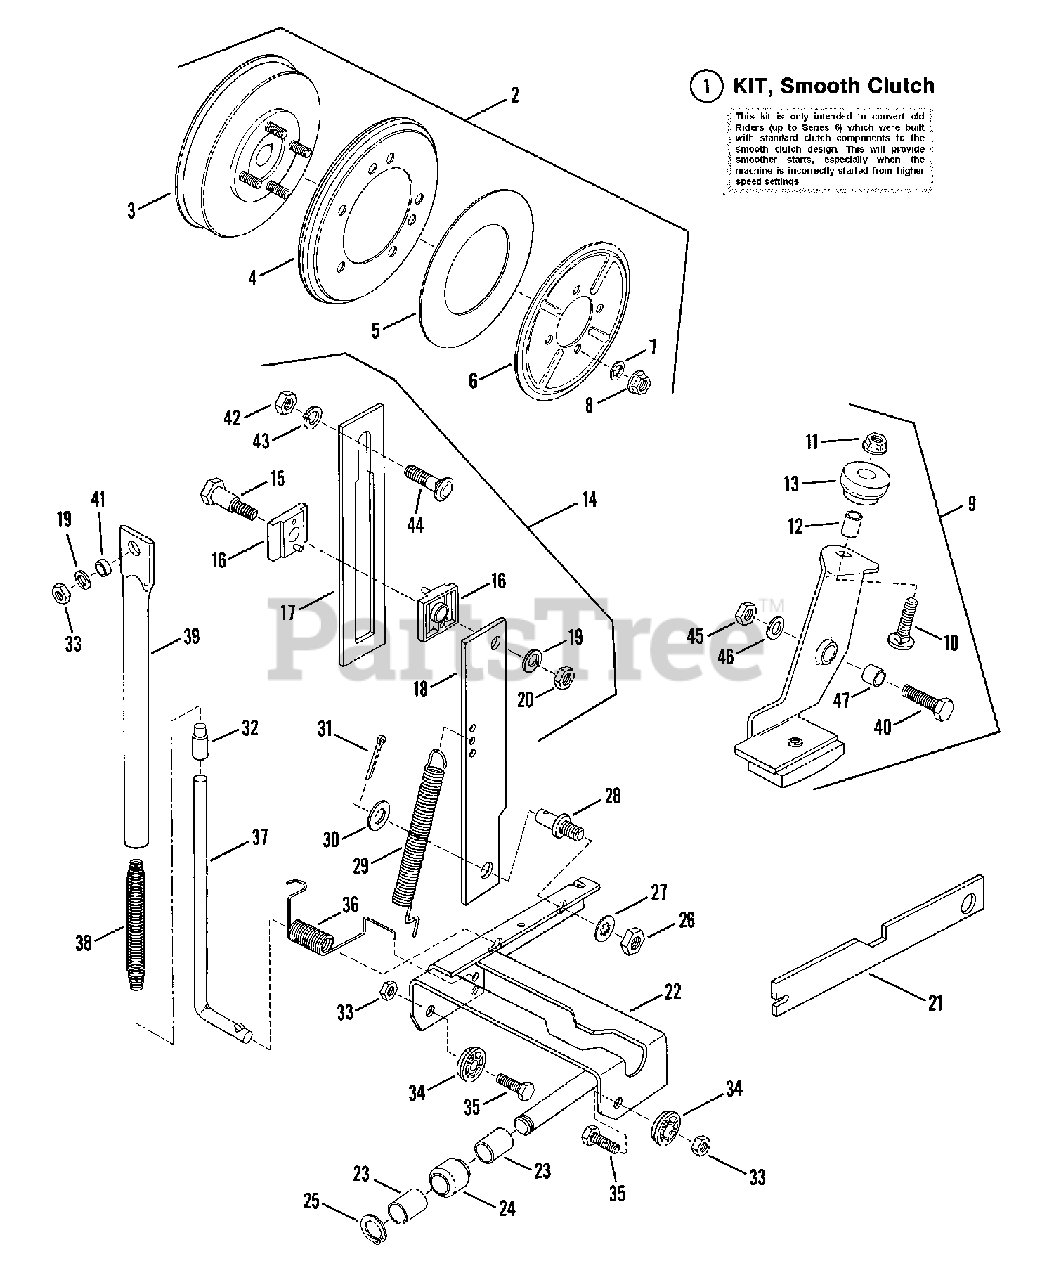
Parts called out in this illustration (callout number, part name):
1	KIT, Smooth Clutch (NLA)
2	ASSEMBLY, Smooth Clutch
3	HUB, Driven Disc
4	DISC, Driven
5	WASHER, Thrust
6	PLATE
7	WASHER, 5/16 Internal Lock
8	NUT, 5/16-18 Hex Flange Lock
9	ASSEMBLY, Brake Lever
10	BOLT, 1/4-20 x 1" Flat Head Carriage
11	NUT, 1/4-20 Hex Flange Lock
12	BUSHING
13	ROLLER, Brake
14	ASSEMBLY, Guide & Link
15	BOLT, 5/16-18 Shoulder
16	SIDE HALF
17	GUIDE, Clutch Link
18	LINK, Clutch
19	WASHER, 5/16 Split Lock
20	NUT, 5/16-18 Hex
21	TOOL, Smooth Clutch
22	LIFT, Yoke
23	SPACER, Roller
24	ROLLER, Park Brake
25	RING, 1/2" External Retaining
26	NUT, 3/8 Hex
27	WASHER, 3/8 Internal Tooth Lock
28	STUD, Clutch Link
29	SPRING, Clutch Brake
30	WASHER, 3/8" Flat
31	PIN, 3/32 x 1" Cotter
32	SPACER, Spring Plug
33	NUT, 5/16-24 Hex Lock
34	BEARING, Yoke
35	SCREW, 5/16-24 x 3/4" Hex Head Cap
36	SPRING
37	ROD
38	SPRING
40	SCREW, 1/4-28 x 1" Hex Head Cap
41	ROLLER
42	NUT, 3/8-16 Hex
43	WASHER, 3/8 Split Lock
44	BOLT, 3/8-16 x 3/4" Short Neck Carriage
45	NUT, 1/4-28 Hex Top Lock
46	WASHER, 1/4 SAE
47	SPACER
